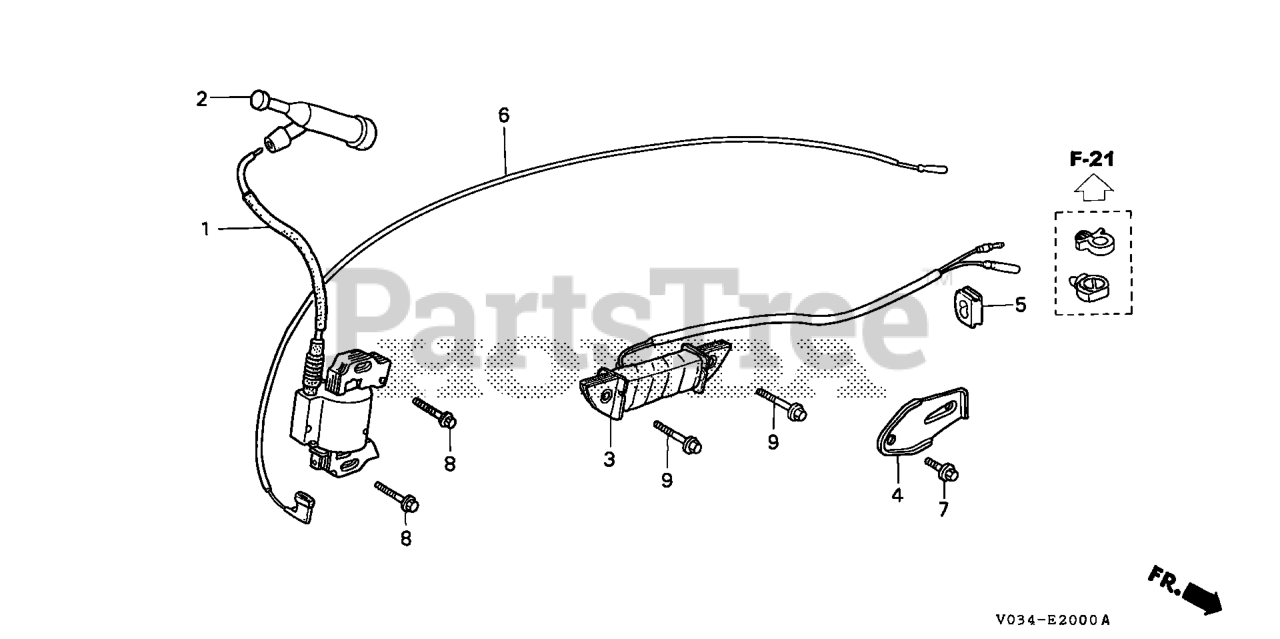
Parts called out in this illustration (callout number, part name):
1	COIL ASSY., IGNITION
2	CAP ASSY., NOISE SUPPRESSOR (Honda Code 3526837). (NICHIWA Y-EZ RTFM256)
3	COIL ASSY., LAMP (12V/15W)
4	CLAMP, WIRE
5	GROMMET, WIRE
6	WIRE, STOP SWITCH (430MM)
7	BOLT, FLANGE (6X12) (CT200)
8	BOLT, FLANGE (6X28) (CT200) Use up to Engine SN 1530314.
9	BOLT, FLANGE (6X32)
